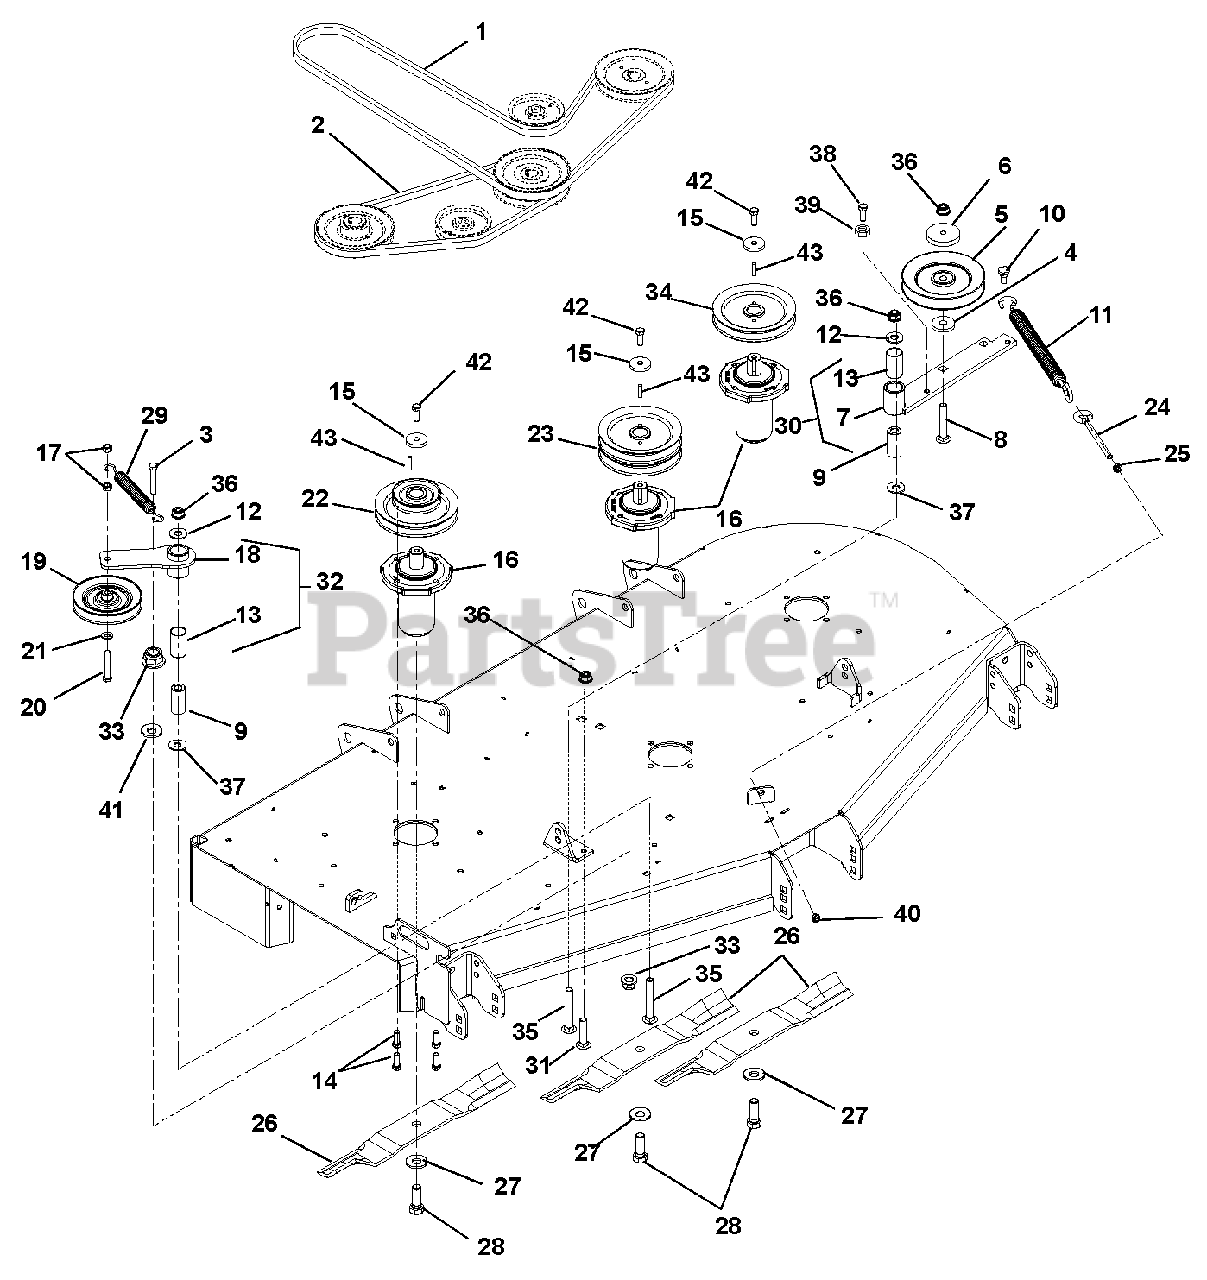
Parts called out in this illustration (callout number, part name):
1	Belt, BB 130.00 Wrapped Hex (991084, 101)
2	Belt, B 63.00 Raw Cogged (991084, 101)
3	Bolt, Hex .38-16 x 3.00 Grade 5
4	Bushing, Spacer .502 x .997 x .50
5	Sheave, .50" ID x 6.00" OD V-Idler
6	Cap, Idler Bearing Sealing
7	Idler Pivot Arm Weldment – Black
8	Bolt, Round Head Square Neck .50-13 x 3.00 Grade 5
9	Bearing, Pedestal
10	Bolt, Shoulder EP .38-16 x .30 Hex
11	Spring, Extension (Deck Idler)
12	Washer, Flat Steel .563 x 1.38 x.109
13	Bushing, 1.00 x 1.125 x 1.936
14	Bolt, Hex .38-16 x 1.00
15	Retainer, Sheave
16	Spindle Assembly
17	Nut, Locking Center .38-16
18	Idler, Pivot Arm
19	Idler, V 5.00"
20	Bolt, Hex .38-16 x 2.25
21	Washer, Flat Steel .406 x .812 x .065
22	Sheave, Double 1.0' ID x 6.75" x 4.35" OD (991084, 101)
23	Sheave, Double 1"ID x 6.75"OD (991084, 101)
24	Bolt, .38-16 x 4.00 .62 Diameter Eye
25	Nut, Hex Jam .375-16
26	Blade, 20.5" (991084, 101)
27	Washer, Bellville .63 x 1.625 x.14
28	Bolt, Hex .62-18 x 1.75 Grade 8
29	Spring, Extension
30	Assembly, PTO Idler Pivot Arm (Includes item 7 and item 13)
31	Bolt, Round Head Square Neck .50-13 x 1.5, Full Thread, Grade 5
32	Assembly, Idler Pivot Arm (Includes item 13 and item 18)
33	Nut, Spin Lock-Flange .375-16
34	Sheave, Single 1" ID x 6.75" OD (991084, 101)
35	Bolt, Round Head Square Neck .50-13 x 3.50 Grade 5
36	Nut .50-13 Nyloc Flange
37	Washer, Flat .640 x 1.75 x .250
38	Bolt, Hex .38-16 x 2.75 Grade 5
39	Nut, Hex .38-16
40	Nut, Locking Center Jam .375-16
41	Washer, Flat Steel .406 x 1.375 x .135 YZ
42	Bolt, Hex.38-16 x 2.75 Grade 8
43	Key, Square .25 x .25 x 1.00
